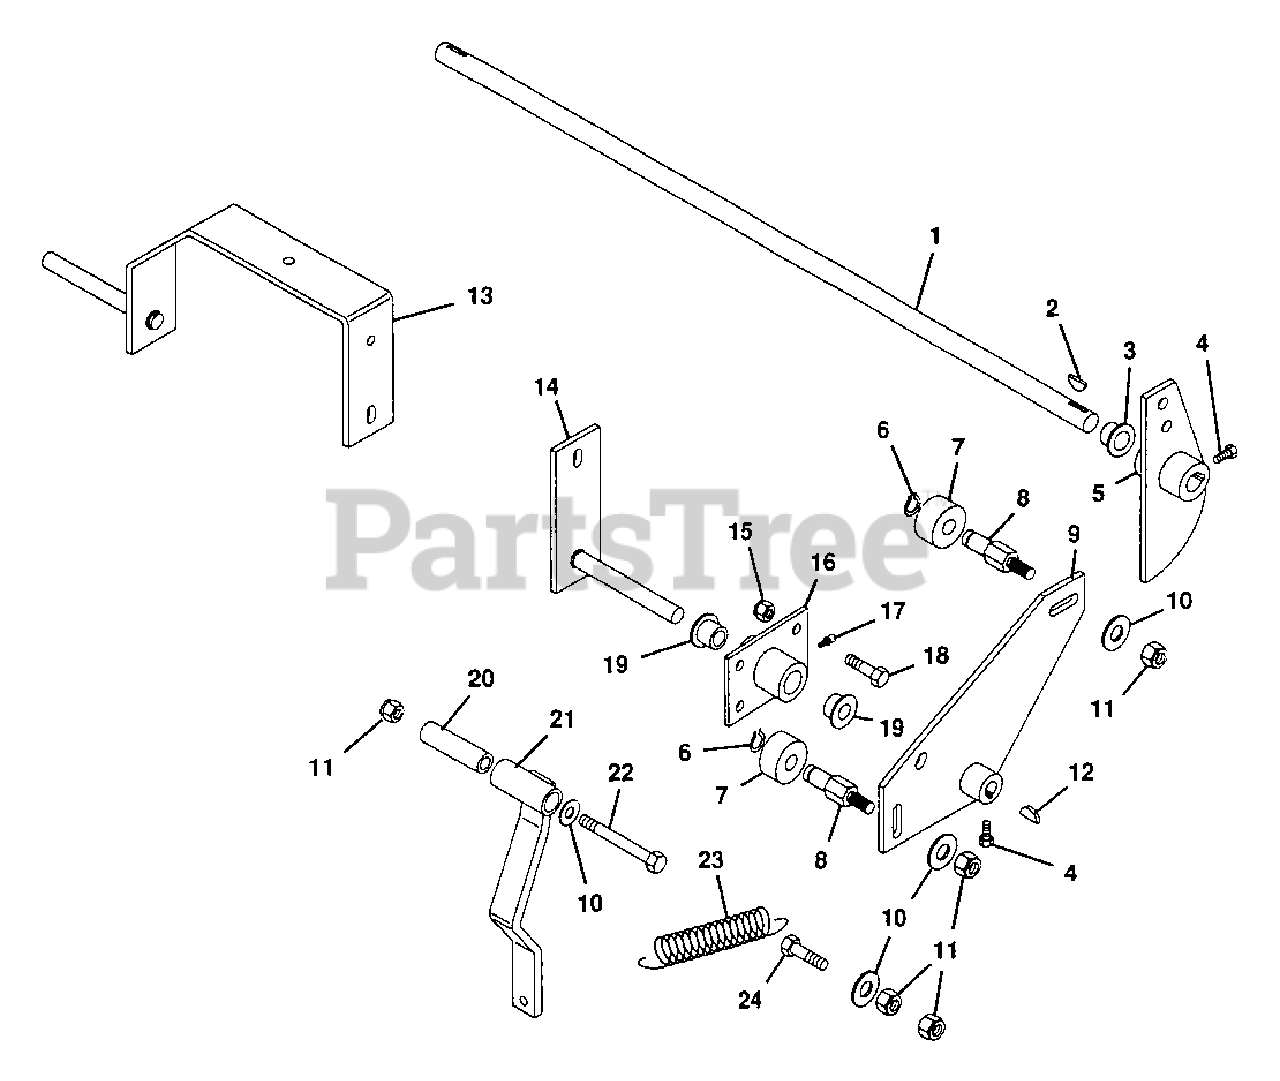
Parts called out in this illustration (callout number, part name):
1	Shaft, Speed Control Cam
2	Key, Woodruff .187x1.00 Hrd. #13
3	Bush., Flg. .630x1.00x.625 Ny.
4	Bolt, Hex 1/4-20x.50
5	Weldment, Control Cam
6	Ring, Retaining .500 Shaft
7	Roller, Nylon
8	Pin, Roller
9	Weldment, Control Arm
10	Washer, Flat .406x.812x.065
11	Nut, Lock 3/8-15
12	Key, Woodruff .125x.75
13	Weldment, Pump Control R.H.
14	Weldment, Pump Control L.H.
15	Nut, Lock 5/16-18
16	Weldment, Bushing Support
17	Fitting, Lube 1/4-28
18	Bolt, Hex 5/16-18x.75
19	Bush., Flg .515x1.00x.745 Ny.
20	Bush., St. .385x.610x1.80 Stl.
21	Weldment, Detent Strap
22	Bolt, Hex 3/8-16x2.75
23	Spring, Ext. LE-063F-5
24	Bolt, Hex 3/8-16x1.50
